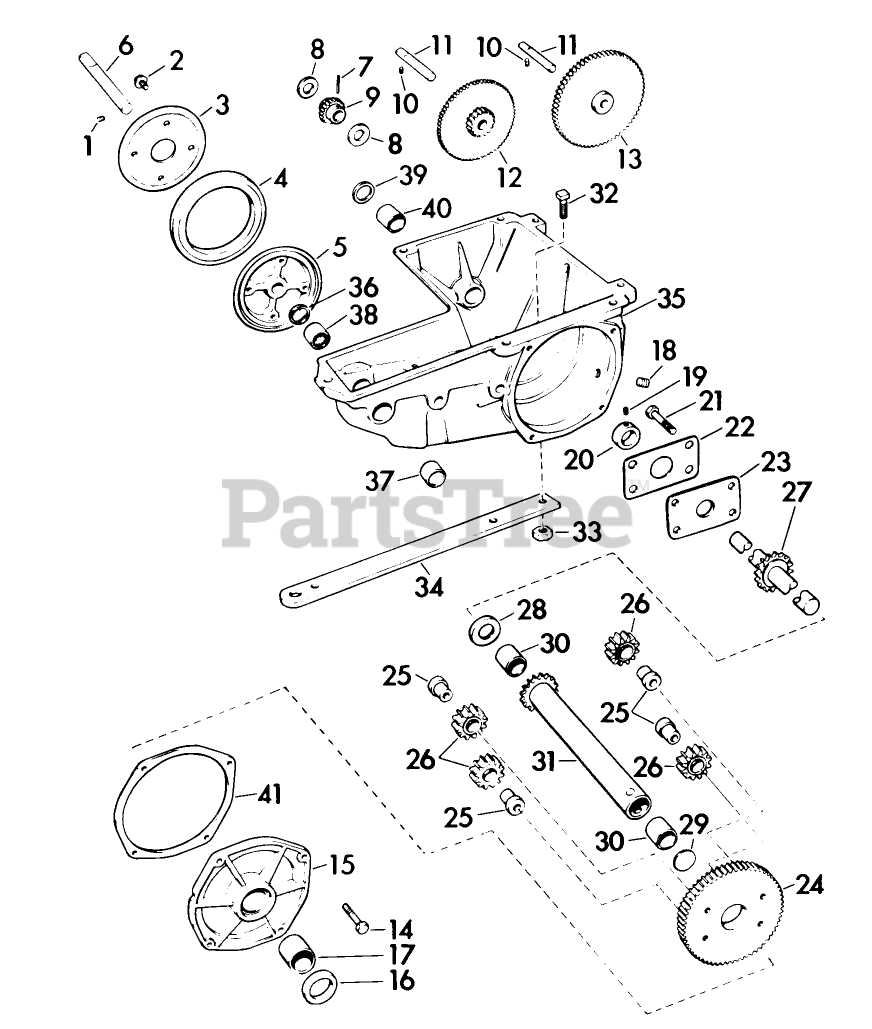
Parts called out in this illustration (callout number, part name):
10	SET SCREW
21	Screw-Differential
24	Gear-Reduction (No. 3)
26	Gear-Planet, Differential
34	Bar-Draw
